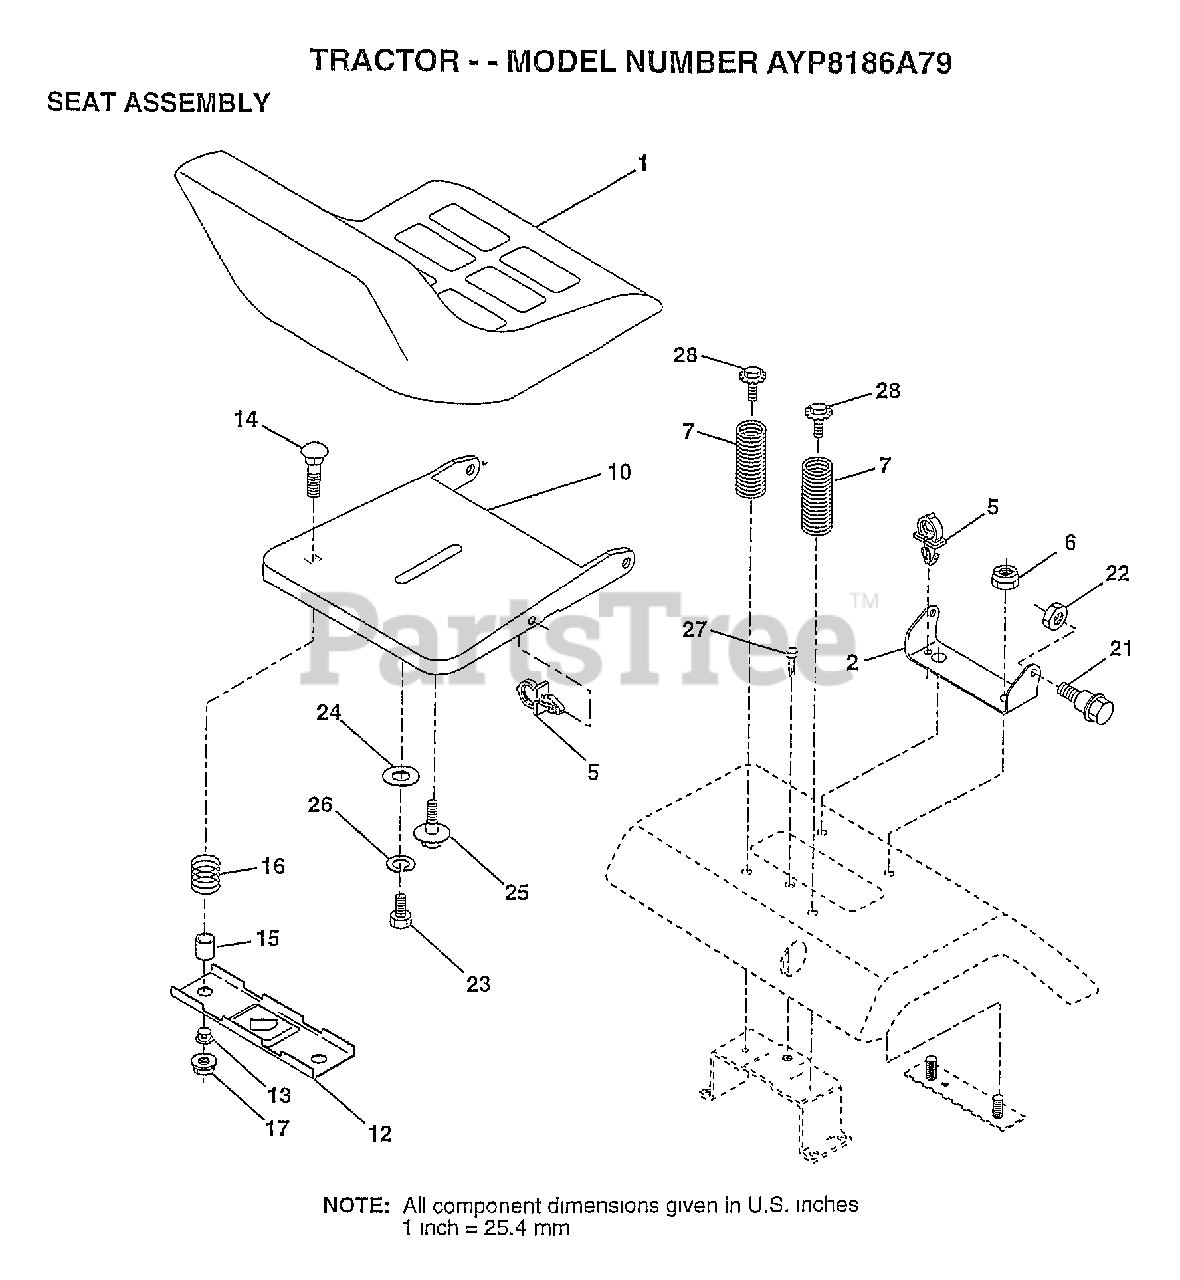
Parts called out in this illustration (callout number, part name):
1	SEAT.2400/1416.BK
2	BRACKET PVT SEAT
5	CLIP.PUSH-IN.HING
6	NUT
7	SPRING COMPRESSIO
10	PAN-SEAT
12	BRKT SWITCH
13	BUSHING
15	SPLIT SPACER
21	"BOLT,SHOULDER"
22	NUT
23	BOLT
24	WASHER
25	"BOLT,SHOULDER"
26	LOCKWASHER
27	SCREW LT
28	BOLT.5/16-18.UNC
